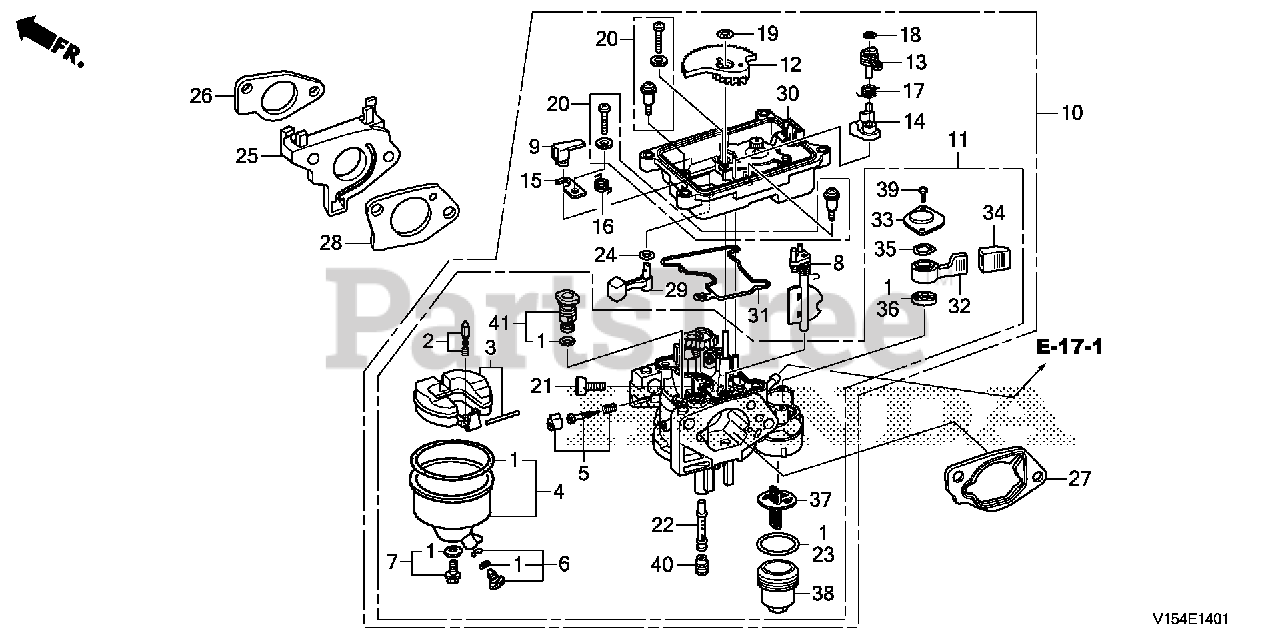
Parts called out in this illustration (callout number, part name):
1	GASKET SET (CARBURETOR NO.)
2	VALVE SET, FLOAT
3	FLOAT SET (CARBURETOR NO.)
4	CHAMBER SET, FLOAT
5	SCREW SET (Honda Code 4219879). (CARBURETOR NO.)
6	SCREW SET, DRAIN (CARBURETOR NO.)
7	SCREW SET (CARBURETOR NO.)
9	ARM, MANUAL START
10	CARBURETOR ASSY. (BE92E B)
11	CARBURETOR SET
12	GEAR, MIDDLE
13	ARM, CHOKE
14	LEVER, CHOKE CONTROL
16	SPRING, TORSION COIL
17	SPRING, TORSION COIL
18	CLIP, SPECIAL
19	CLIP, SPECIAL
21	SCREW, STOP
22	NOZZLE, MAIN
23	GASKET, FUEL STRAINER CUP
24	O-RING (CARBURETOR NO.)
25	INSULATOR, CARBURETOR
26	GASKET, CARBURETOR INSULATOR
27	SPACER, CARBURETOR
28	GASKET, CARBURETOR
29	LEVER, MANUAL START
30	CASE, MOTOR
32	LEVER, VALVE
33	PLATE, LEVER SETTING (CARBURETOR NO.)
34	CAP, LEVER
35	SPRING, PETCOCK LEVER (CARBURETOR NO.)
36	GASKET, VALVE
37	FILTER, CUP (CARBURETOR NO.)
38	CUP, FUEL STRAINER
39	SCREW, PAN (3X6)
40	JET, MAIN (#98) Use from Engine SN BE87A A to BE87A A.
40	JET, MAIN (#102) (ADVENTURE GREEN) (CARBURETOR NO.)
40	JET, MAIN (#105) Use from Engine SN BE87H A.
41	JET SET, PILOT (#45) (CARBURETOR NO.)
41	JET SET, PILOT (#45)
